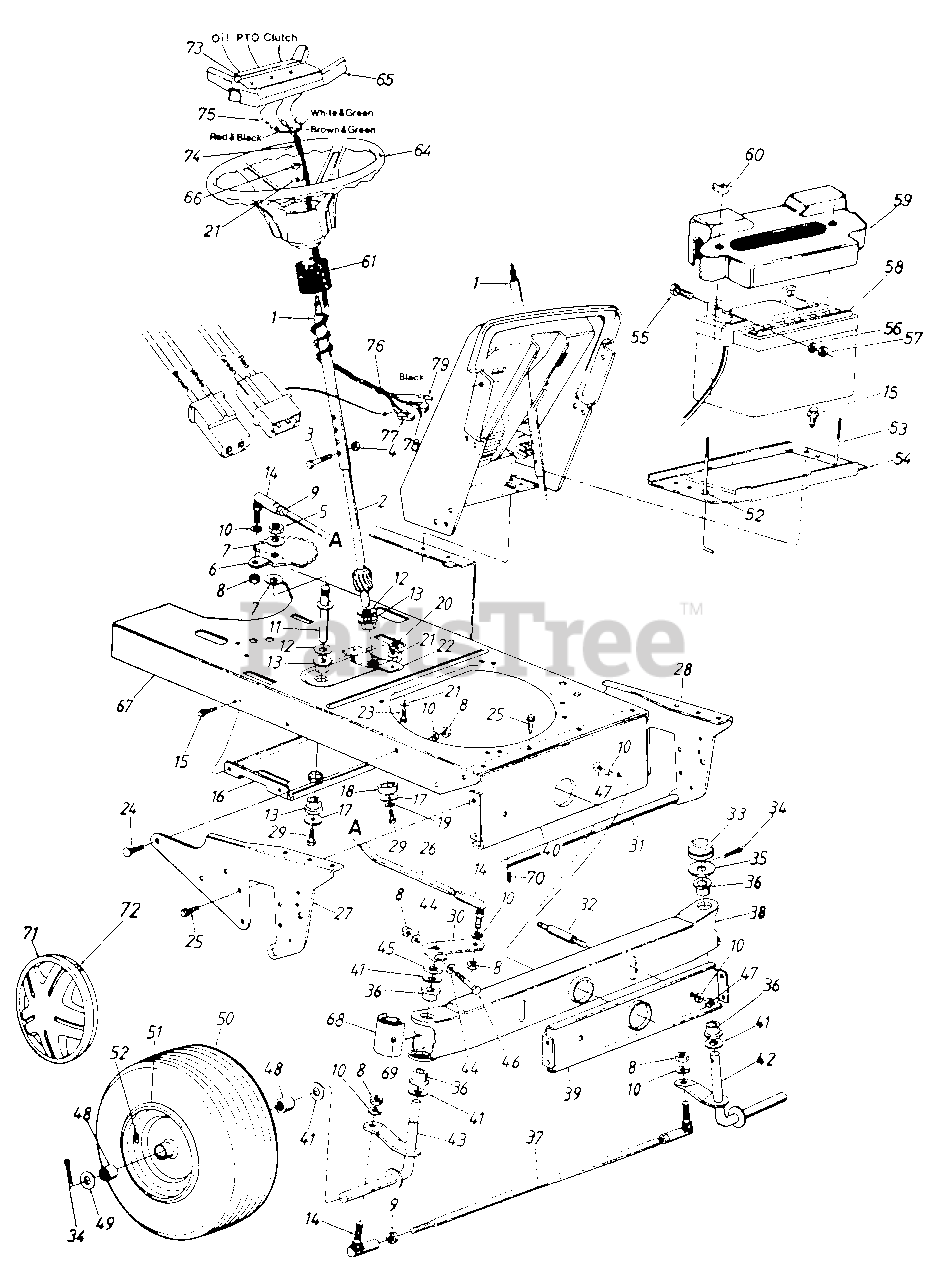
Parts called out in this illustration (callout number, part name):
1	Steering Column Ass'y.
2	Lower Steering Shaft
3	Hex Bolt 1/4-20 x 1.31" Lg.
4	Hex L-Nut 1/4-20 Thd.
5	Hex Nut 5/818 Thd.
6	Steering Gear Segment
7	8ell-Wash. 5/8" I.D. x 1.25" O.D.
8	Hex Nut 3/8-24 Thd.
9	Hex Jam Nut 3/8-24 Thd.
10	L-Wash. 3/8" I.D.
11	Steering Gear Segment Shaft
12	Fl-Wash. .64" I.D. x 1.24" O.D.
13	Hex Flange Brg. .63" I.D.
14	Ball Joint Ass'y.
15	Hex Wash. Hd. TT-Tap Scr. 1/4-20 x .5" Lg.
16	Deck Idler Support Brkt.
17	Fl-Wash. .33" I.D. x 1.25" O.D.
18	Spacer .985" I.D. x 1.25" O.D.
19	L-Wash. 5/16" I.D.
20	Hex Nut 5/16-24 Thd.
21	Bell-Wash. .345" I.D. x .88" O.D.
24	Ribbed Neck Bolt 3/8-24 x .8" Lg.
25	Hex Wash. TT-Tap Scr. 5/16-18 x .62" Lg.
26	Steering Drag Link
27	Pivot Bar Side Plate-R.H.
28	Pivot Bar Side Plate-L.H.
29	Hex Bolt 5/16-18 x .62" Lg.
30	Steering Arm
31	Deck Connecting Rod
32	Pivot Bar Shld. Bolt 3/8-16 x 518" Lg.
33	Cap
34	Cotter Pin 5/32" Dia.
35	Flat Washer
36	Flange Brg. .757" I.D.
37	Tie Rod 20.25" Lg.
38	Pivot Bar Assy.
41	Fl-Wash. .76" I.D. x 1.49" O.D.
42	Front Axle Ass'y.-L.H.
43	Front Axle Ass'y.-R.H.
44	Bowed Washer
45	Spacer .755" I.D. x 1.25" O.D.
46	Hex Bolt 3/8-24 x 2.25" Lg.
47	Hex Nut 3/8-16 Thd.
48	Needle Brg. .75" I.D.
49	Fl-Wash. .71" I.D. x 1.5" O.D.
50	Wheel Ass'y. Comp.
51	Rim Only
52	Push Nut
53	Battery Hold Down Rod
54	Battery Carrier
55	Hex Bolt 1/4-20 x .62" Lg.
56	L-Wash. 1/4" I.D.
57	Hex Nut 1/4-20 Thd.
58	Battery
59	Battery Cover
60	Wing Nut Plastic 1/4-20 Thd.
61	Steering Bellow
64	Steering Wheel
65	Steering Wheel Insert
66	Hex L-Nut 5/16-24 Thd.
67	Lower Frame
68	Pivot Bar End Cap
69	Grease Fitting
70	Internal Cotter Pin
71	Hub Cap
72	Spring Clip
73	Steering Wheel Insert Label
74	Wire Harness
75	Bulb
76	Clamp
77	Connector
78	Connector
79	Connector
